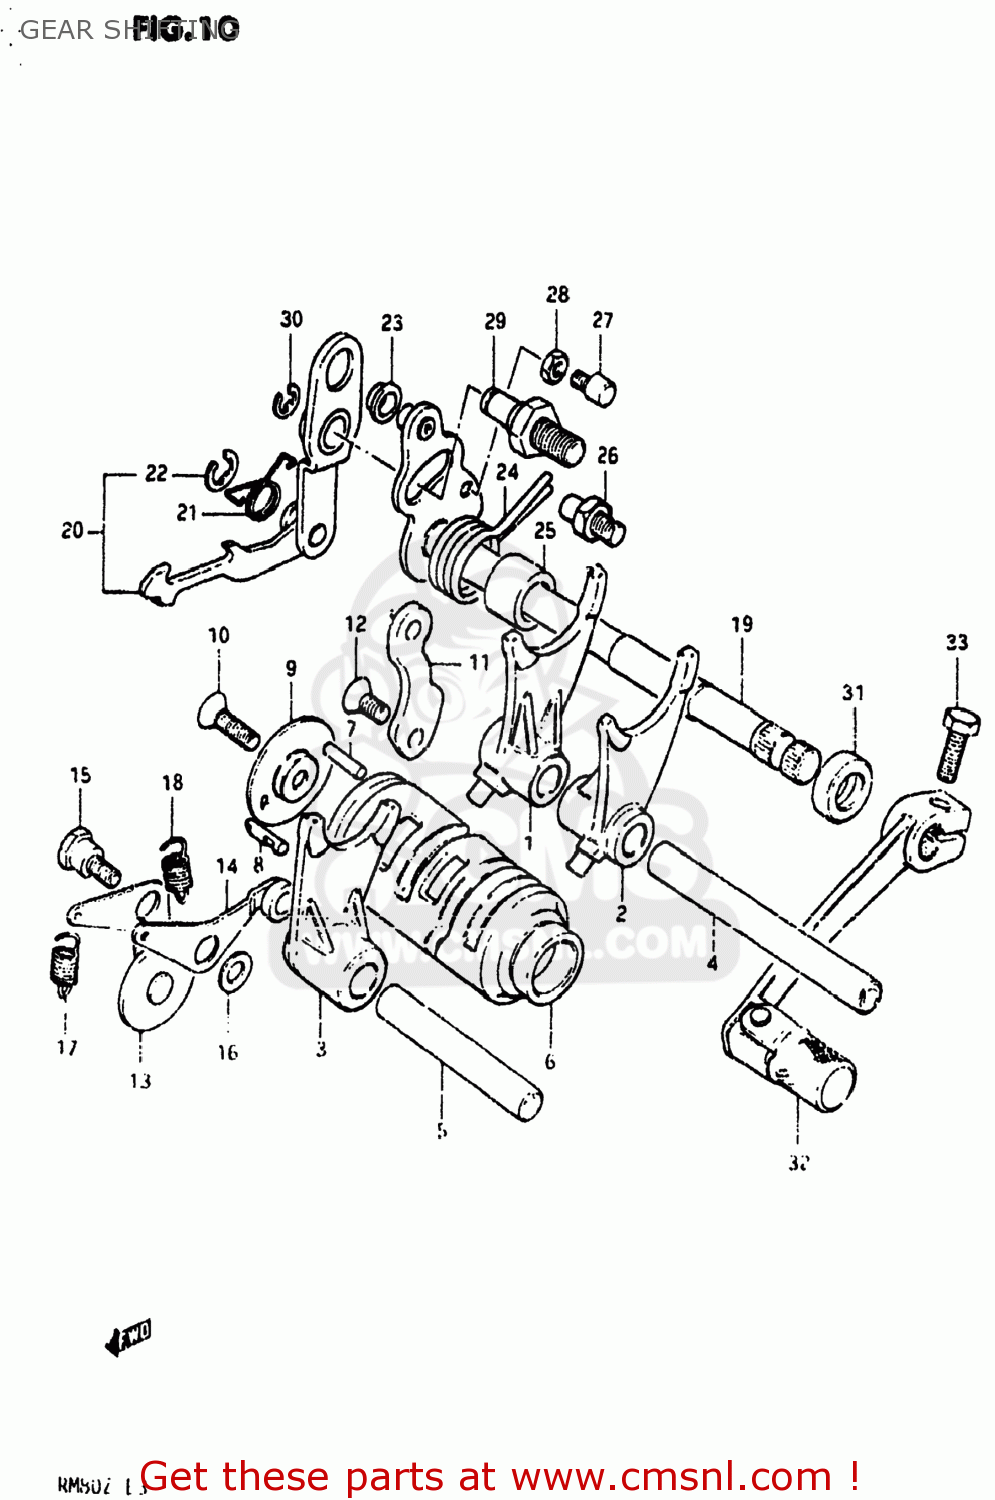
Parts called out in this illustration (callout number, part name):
1	FORK,GEAR SHIFT NO.1
2	FORK,GEAR SHIFT NO.2
3	FORK,GEAR SHIFT NO.2
4	SHAFT,GEAR SHIFT FORK
5	SHAFT,GEAR SHIFT FORK
6	CAM,GEAR SHIFT
7	PIN(4X15.8)
8	PIN
9	RETAINER,GEAR SHIFT CAM
10	SCREW
11	GUIDE,GEAR SHIFTING CABLE
12	SCREW
13	STOPPER,SHIFT CAM
14	STOPPER,GEAR SHIFT CAM
15	BOLT(6X18.3)
16	WASHER
17	SPRING
18	SPRING
19	SHAFT,GEAR SHIFT
20	PAWL,GEAR SHIFT
21	SPRING
22	E RING
23	SPACER(7X10X5)
24	SPRING
25	SPACER(12X20X15.3)
26	STOPPER,GEAR SHIFT CAM
27	BOLT,GEAR SHAFT RETURN SPR SET
28	NUT 6MM
29	STOPPER,GEAR SHIFT CAM
30	E RING 6MM
31	OIL SEAL
32	LEVER ASSEMBLY,GEAR SHIFTING
33	BOLT
